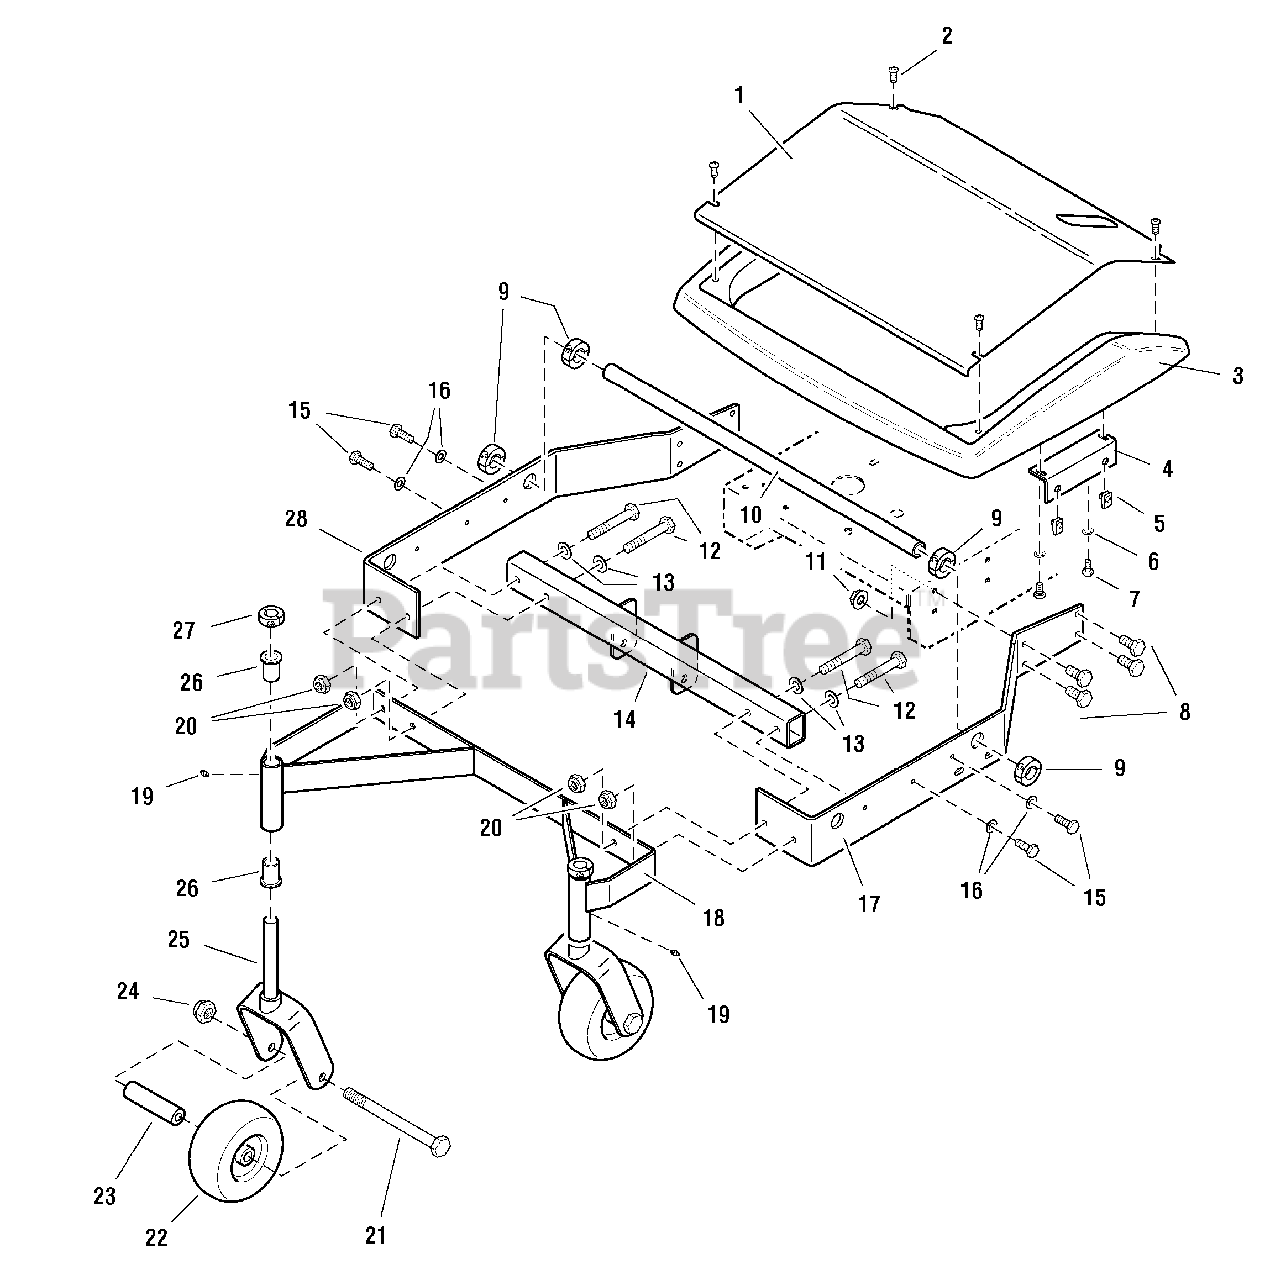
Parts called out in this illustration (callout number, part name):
1	SHIELD INSERT
2	SCREW, Allen Head, 1/4-20 x 1/2
3	GUARD, Mower Deck
4	SHIELD MOUNT BRACKET
5	BODY CLIP, 5/16-18
6	LOCKWASHER, 1/4
7	CAPSCREW, Hex Head, 1/4-20 x 3/4
8	CAPSCREW, Hex Head, 3/8-16 x 1
9	COLLAR, Double Split, 1
11	NUT, Hex Serrated Flange, 3/8-16
12	CAPSCREW, Hex Head, 3/8-16 x 2-1/2
13	WASHER, 3/8
15	BOLT, 1/4-20 X 1", GD
16	WASHER, 5/16
17	FRAME RAIL - LH
18	CASTER MOUNT FRAME
19	GREASE FITTING, 1/4-28
20	NUT, Hex Nylon Lock, 3/8-16
21	CAPSCREW, Hex Head, 1/2-13 x 5-1/2
22	CASTER TIRE
24	NUT, Hex Nylon Lock, 1/2-13
25	CASTER YOKE
26	BUSHING, Flange
27	COLLAR, Split, 3/4
28	FRAME RAIL - RH
